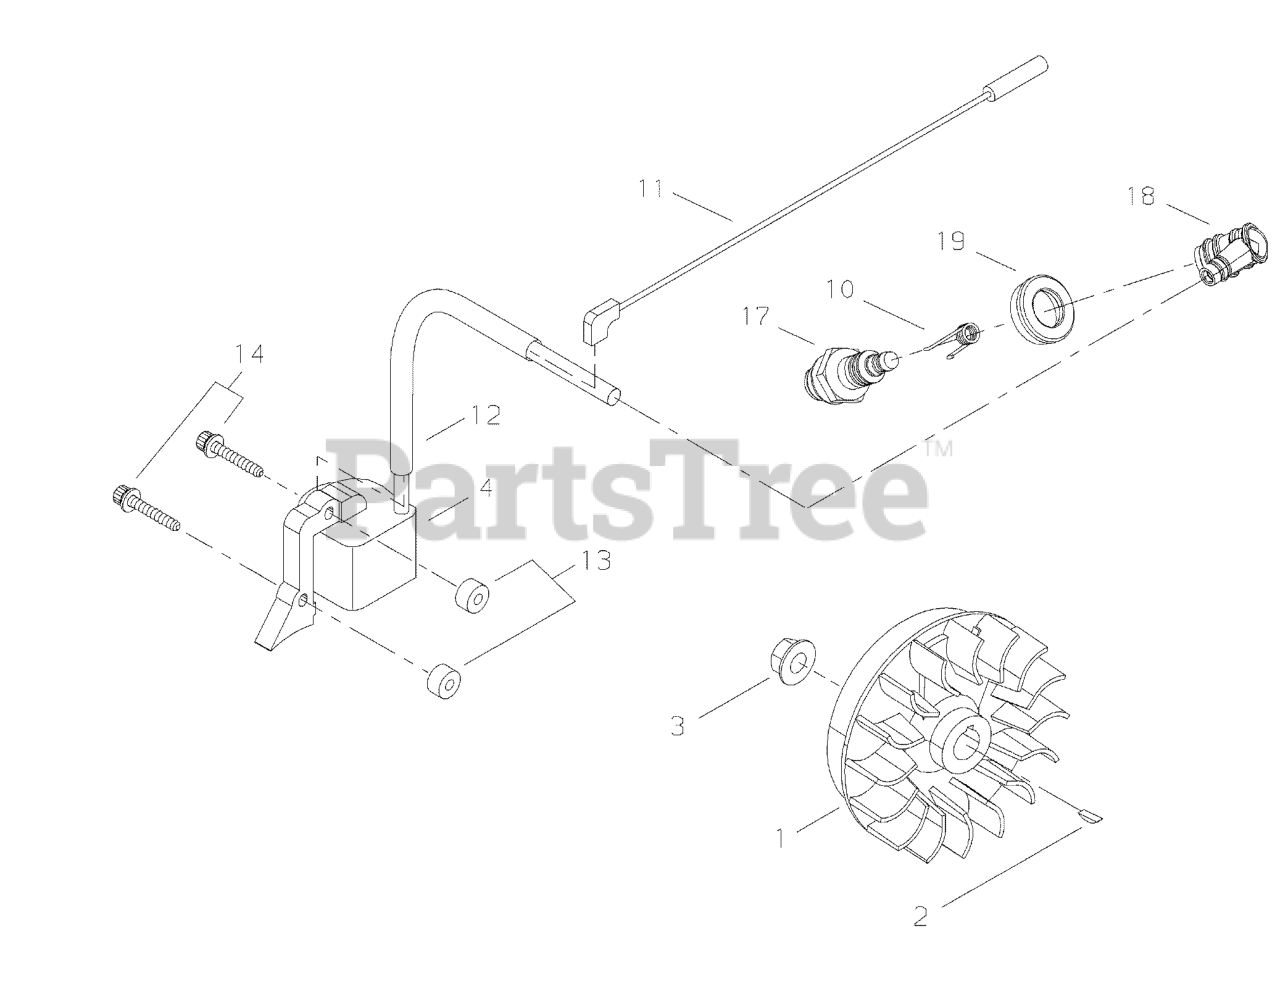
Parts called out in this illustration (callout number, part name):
1	FLYWHEEL
2	KEY - 3X10
3	NUT - 8
4	COIL, IGNITION
10	TERMINAL, SPARK PLUG CAP
11	LEAD - IGNITION
12	TUBE
13	INSULATOR
14	SCREW - 4X20
17	SPARK PLUG -- BPMR-6A
18	CAP, SPARK PLUG
19	SEAL, DUST
